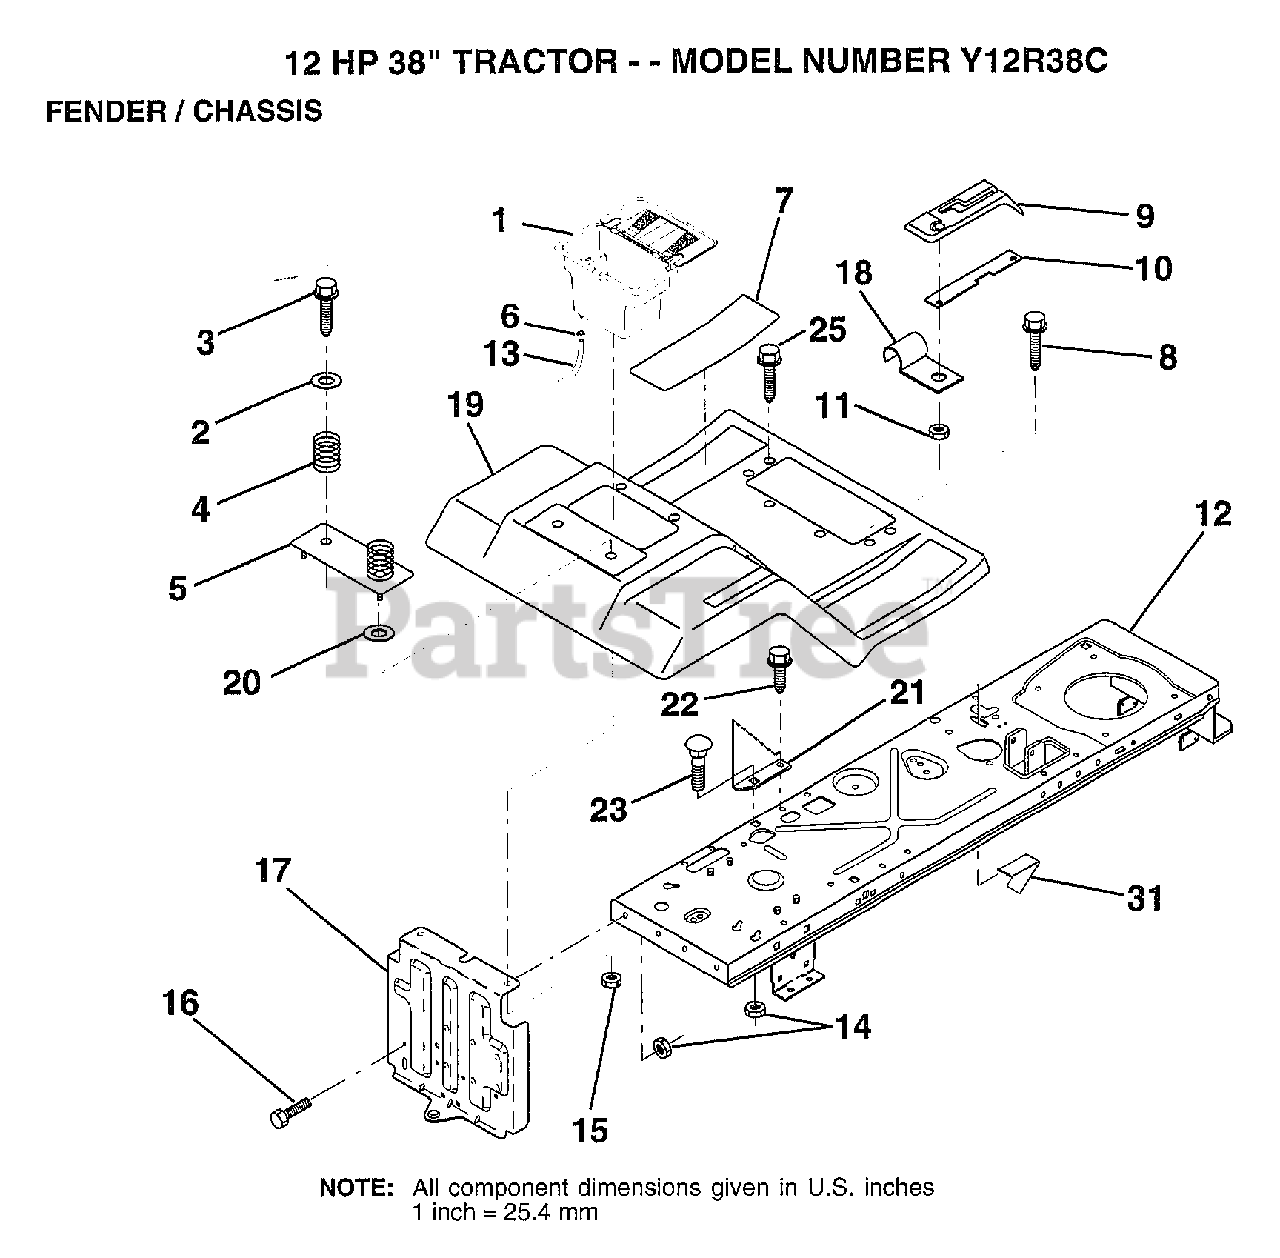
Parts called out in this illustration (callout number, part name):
2	WASHER
3	SCREW
4	SPRING COMPRESSIO
5	BTRY FENDER PLATE
6	HOSE CLAMP T
7	PAD FOOTREST
8	SCREW
10	PLATE LOCK SHIFT
11	NUT
13	TUBE T
14	NUT
15	NUT
16	BOLT
17	DRAWBAR ASM LR
18	"CLIP,INSULATOR"
19	FENDER/FOOT MS505
21	BRACKET STOP DEPT
22	SCREW LT
25	SCREW TI
